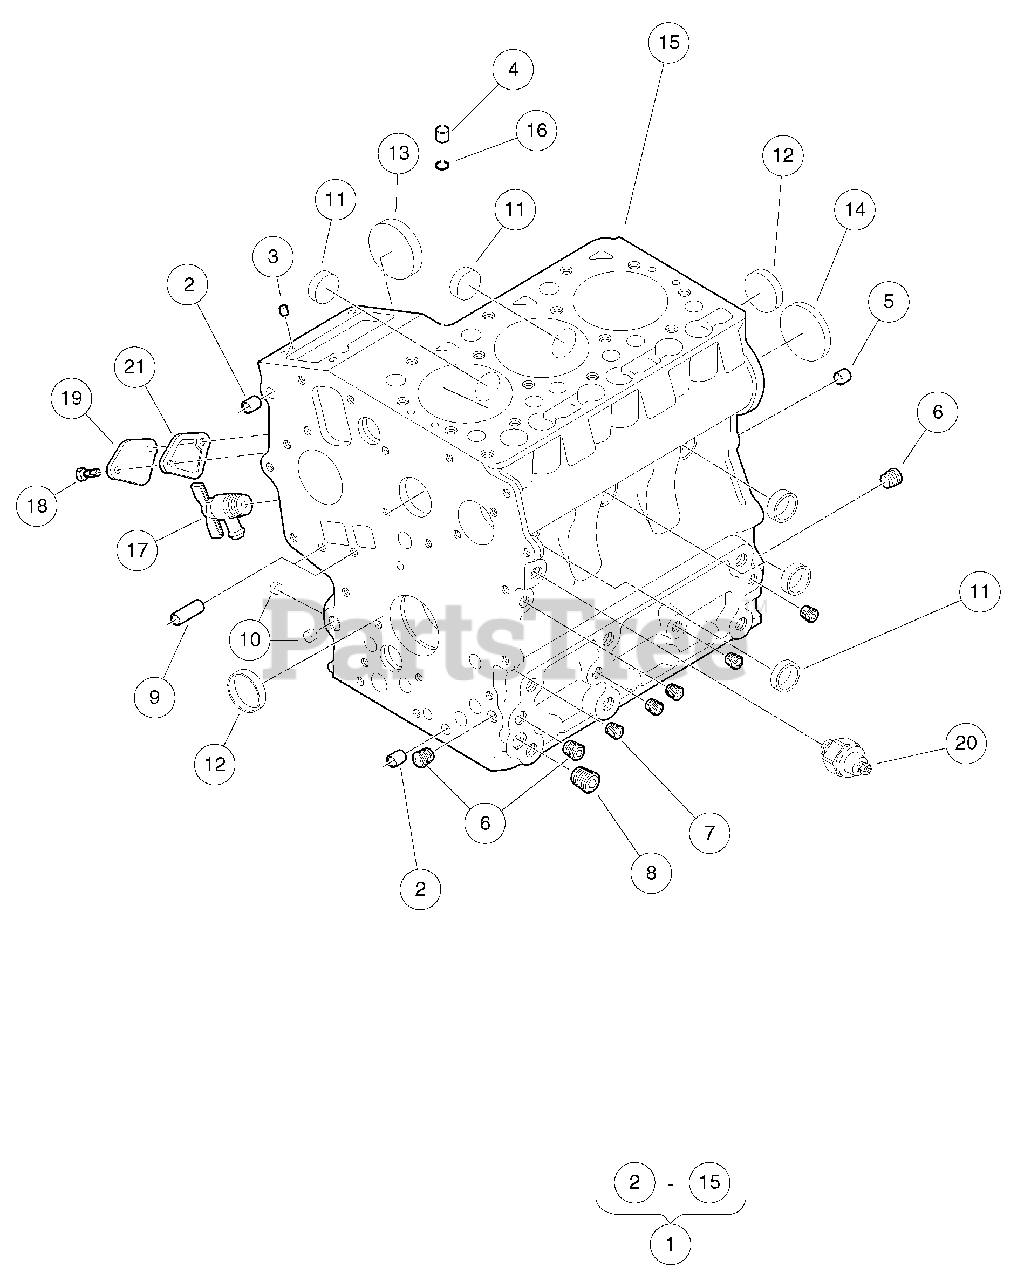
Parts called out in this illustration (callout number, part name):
1	Engine Block
2	Pin, Pipe, Dia 8 X 14
3	Pin, Straight, Dia 5 X 10
4	Pin, Pipe, Dia 7 X 14
5	Pin, Straight, Dia 8 X 16
6	Plug, 1/8"
7	Plug, 3/32"
8	Plug, 1/4"
9	Pin, Pipe, Dia 8 X 11
10	Cap, Sealing, Small
11	Cap, Sealing, Med
12	Cap, Sealing, Large
13	Cover, Fuel Camshaft
14	Plug, Expansion
15	Block, Engine
16	O Ring, 8 X 7
17	Cock, Drain
18	Bolt, M6 X 1 X 20
19	Plate, Engine Block
20	Switch, Oil Pressure
21	Gasket, Fuel Pump, D722
